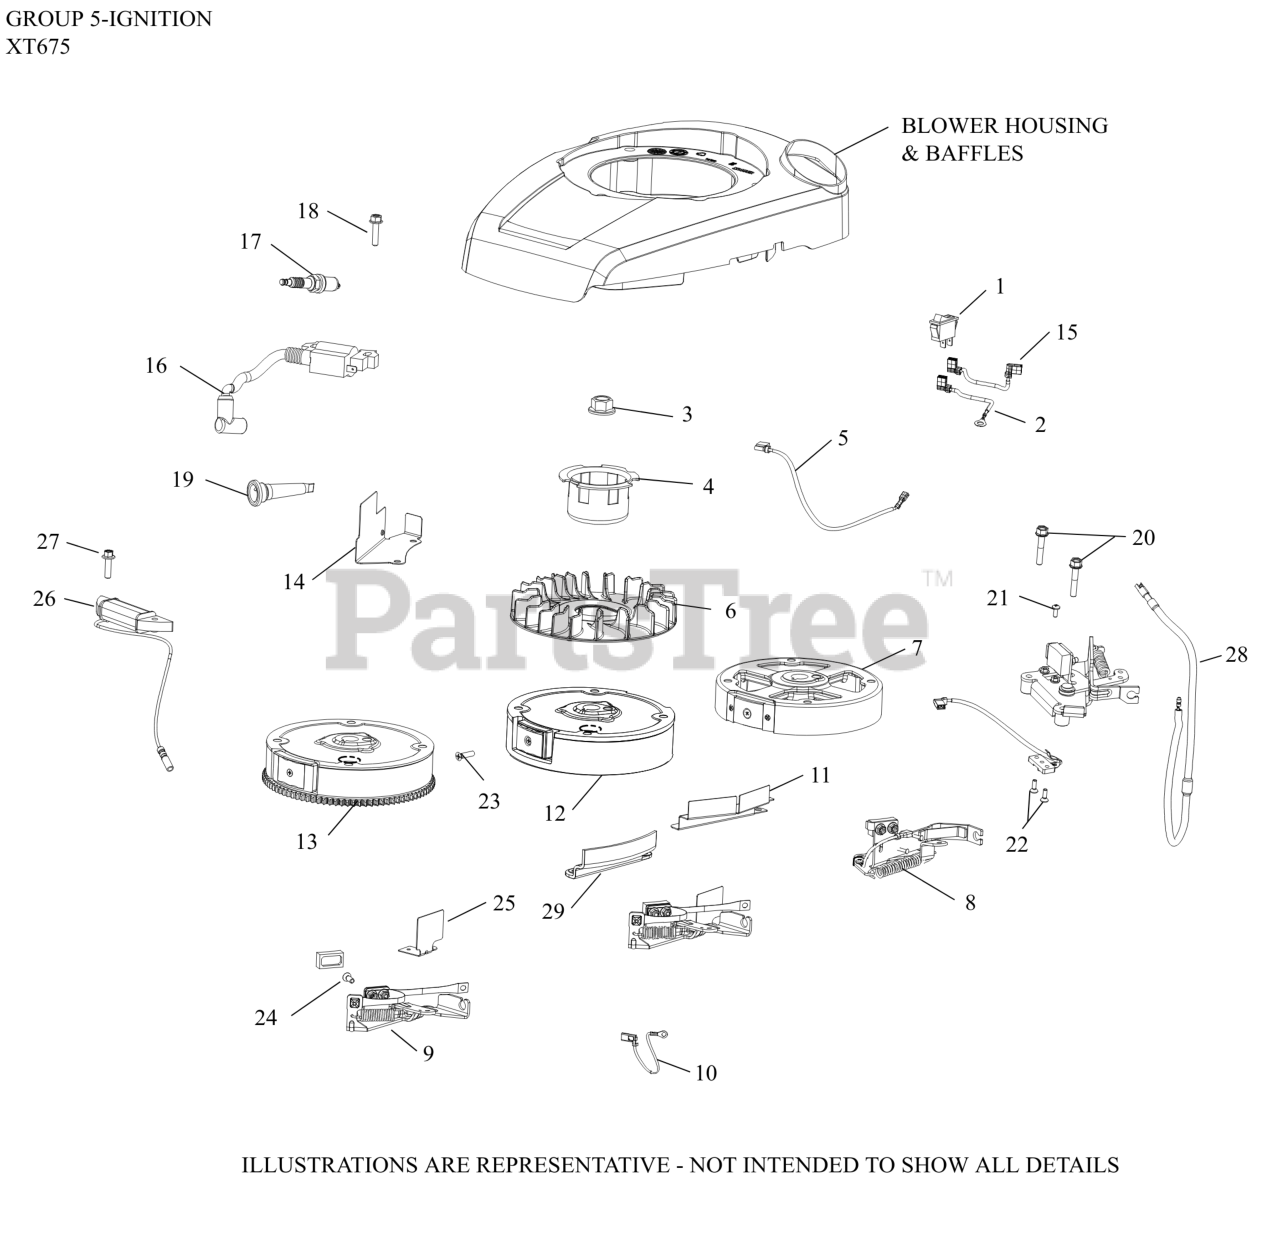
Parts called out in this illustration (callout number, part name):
3	NUT, FLYWHEEL (W/SERRATIONS)
4	CUP, STARTER DRIVE
6	FAN, FLYWHEEL
7	FLYWHEEL ASSEMBLY-USE 14 025 12-S
9	BRAKE, ASSEMBLY-USE 14 219 17-S
10	LEAD, KILL-USE 14 518 28-S
10	LEAD, KILL (BRAKE TO IGN MODULE)
14	GUARD, FINGER
16	MODULE IGN (#1458416S)
17	PLUG SPARK 12MM RFI
25	GUARD, BRAKE - USE 14 314 30-S
